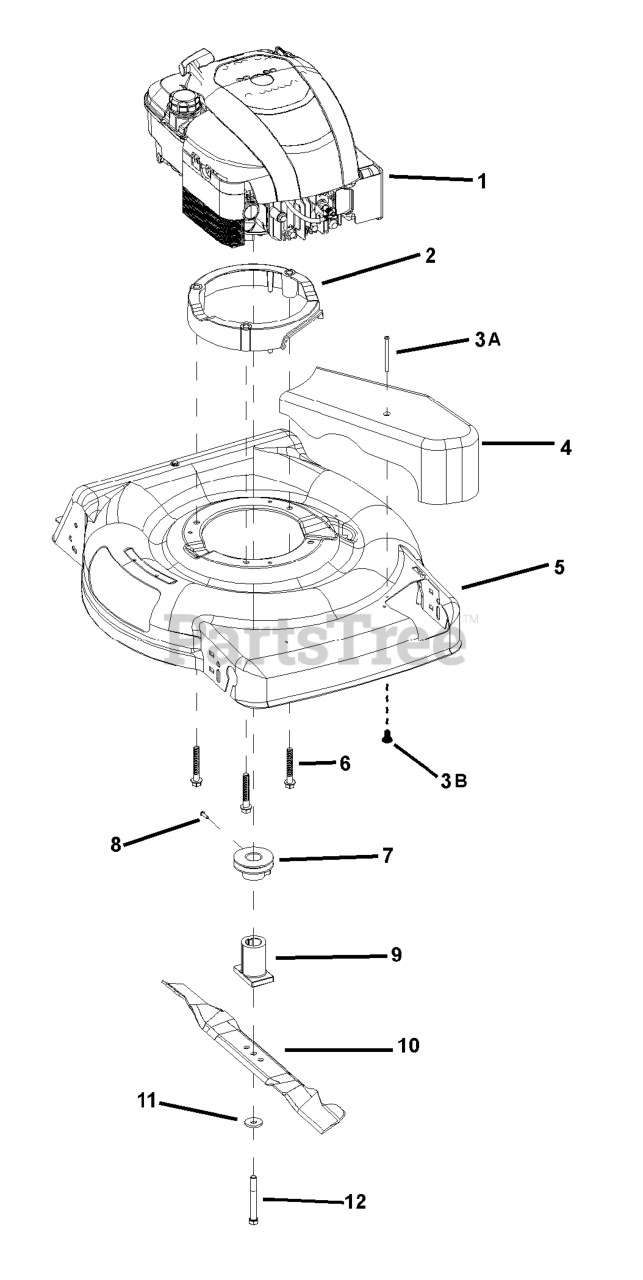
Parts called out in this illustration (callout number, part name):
2	ASSY, ENGINE SPACER , 22 WBM, PROPELLED
3A	SCREW, #10-24 X 2-1/2
3B	SCREW, Round Washer Head Torx, Hi-Lo
4	COVER, BELT, PLASTIC (shown)
5	DECK, 22 WALK, 3-N-1
6	BOLT, 3/8-16 NS X 2.50"
7	PULLEY, ENGINE, 22 DECK, SS
8	SCREW, #8-11 X .63 POLY
9	HUB, BLADE, 22 DECK
10	BLADE, 22, WALK MOWER
11	WASHER, BELLVILLE, .38 ID X 1.183 OD
12	BOLT, HEX HEAD, 3/8-24 NF X 3.25
